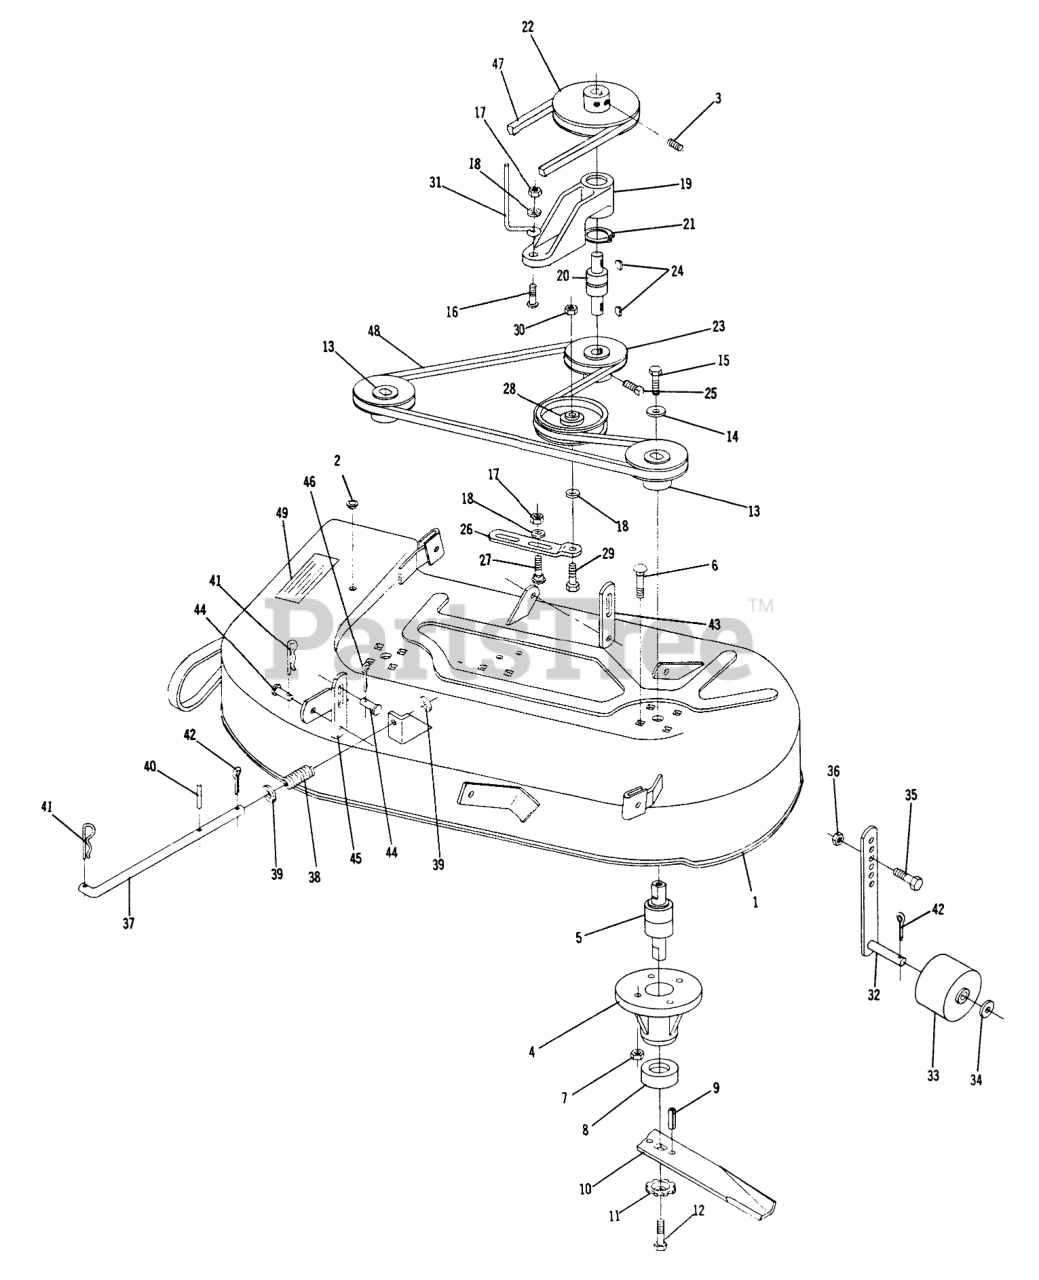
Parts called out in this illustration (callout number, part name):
2	Plug Button
3	Set Screw
6	Bolt Carriage 3/8-16 x 1
7	Nut Crownlock 3/8-16
9	SPIROL ROLL PIN
12	Bolt 3/8-16 x 7/8
14	WASHER
15	Bolt 3/8-16 x 3/4 Nylok
16	Bolt 3/8-16 x 1
17	3/8-16 E.S.
18	Washer
20	Bearing-Integral Shaft 5/8
24	KEY-WOODRUFF
25	Set Screw-5/16-18 x 3/8
27	Bolt 3/8-16 x 1
29	Bolt Hex 3/8-16
30	Nut Crownlock 3/8-16
33	ROLLER ASSY
34	Washer
35	Bolt 5/16-18 x 1
36	Nut 5/16-18
37	Rod-Link
38	Spring
39	Washer
40	PIN-ROLL
41	Hairpin
42	Cotter Pin
43	LIFT LINK
44	Clevis Pin 3/8 x 3/4
46	Hairpin
